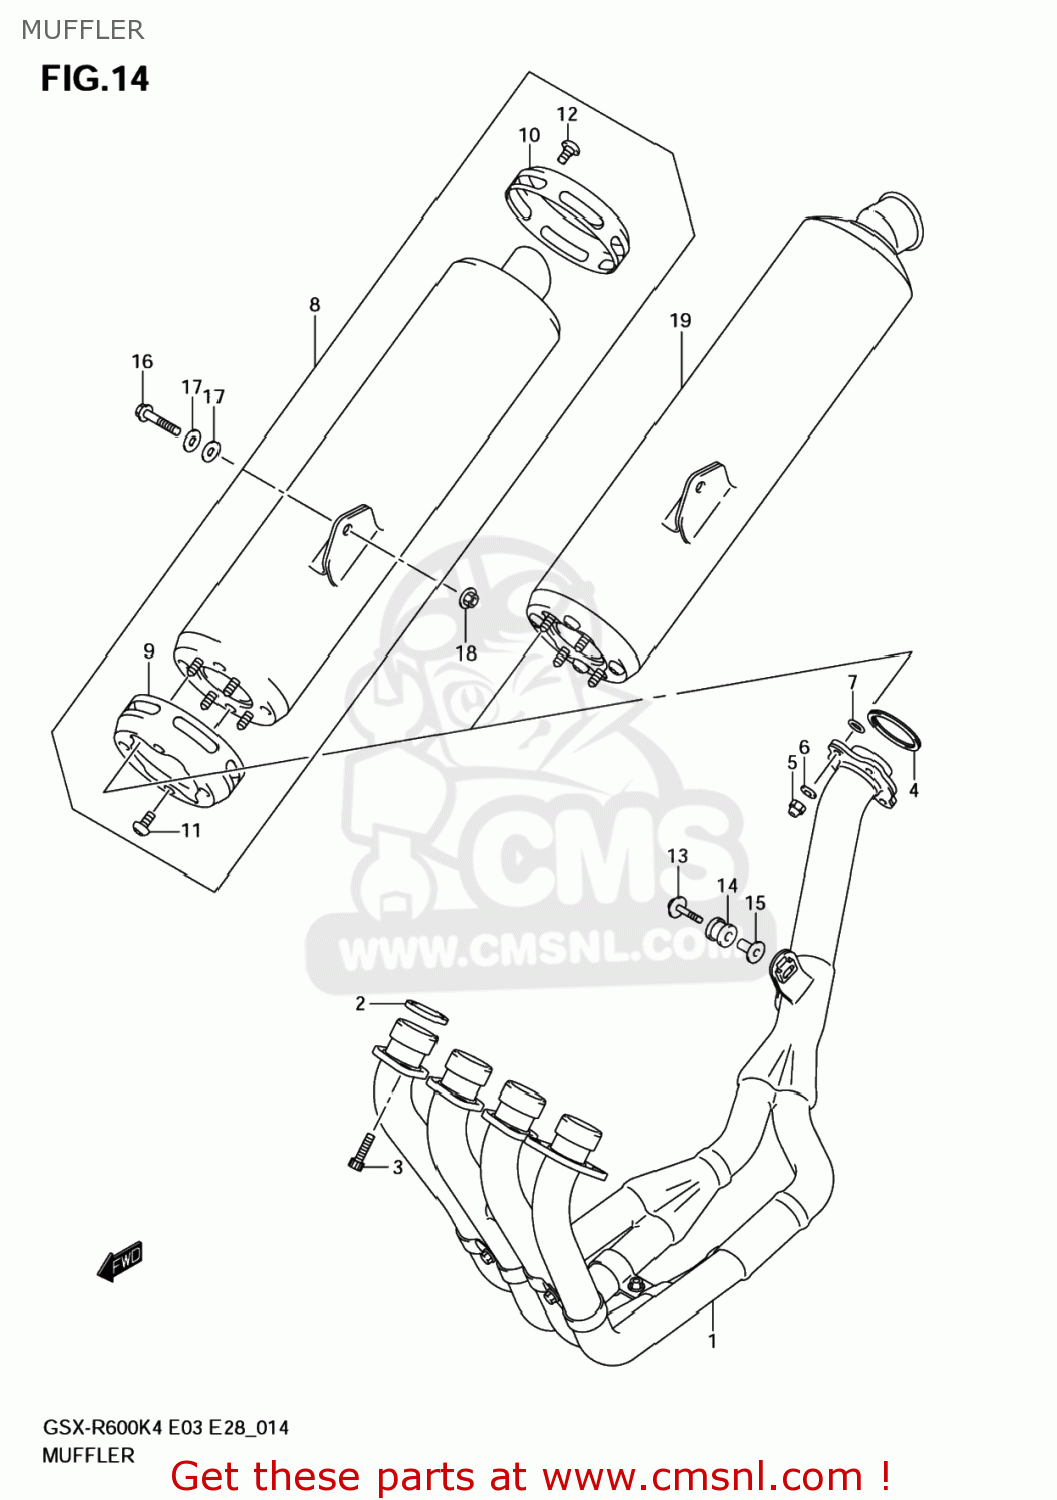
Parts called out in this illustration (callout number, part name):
1	EXHAUST
2	GASKET,EXHAUST PIPE
3	BOLT
4	GASKET,MUFFLER JOINT (NAS)
5	NUT
6	WASHER(8.5X18X1.6)
7	O RING(D:1.9,ID:7.8)
8	BODY,MUFFLER
9	COVER,MUFFLER FR
10	COVER,MUFFLER RR
11	SCREW,MUFFLER COVER FR
12	SCREW(6X10)
13	BOLT 8X45
14	CUSHION
15	SPACER(8.6X12X24.2)
16	BOLT(8X40)
17	WASHER(8.5X23X1.5)
18	NUT
19	BODY,MUFFLER
